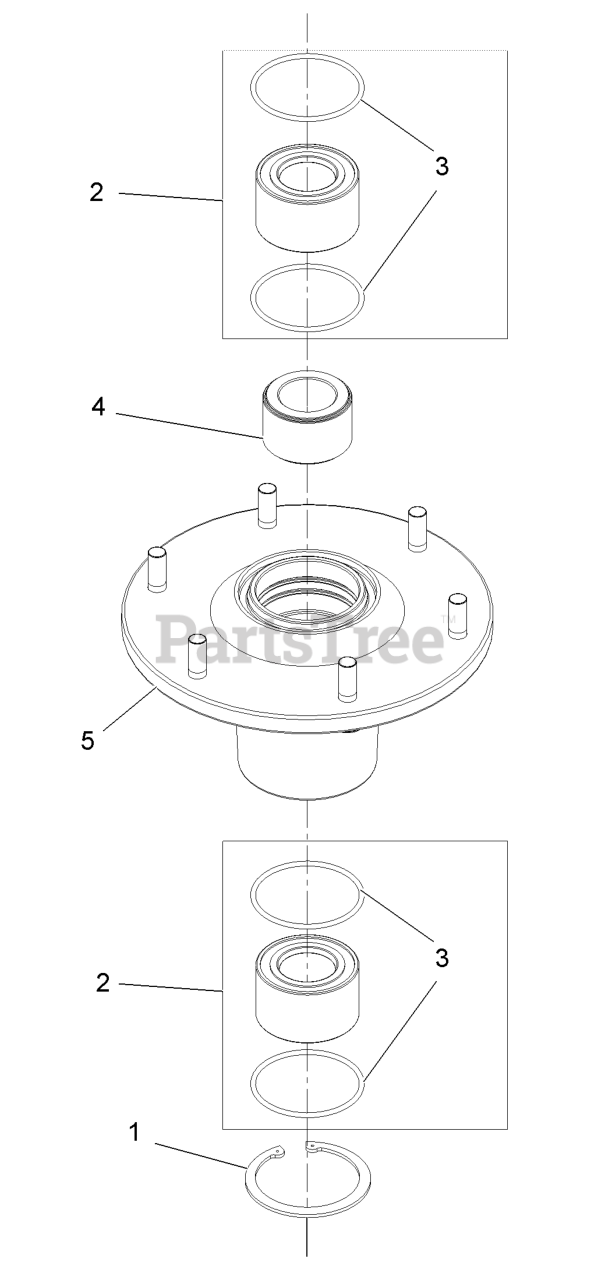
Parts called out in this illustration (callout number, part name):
1	Ring-Retaining
2	Asm, Bearing W/O-Rings
4	Spacer, Bearing
5	Asm, Housing W/Studs
